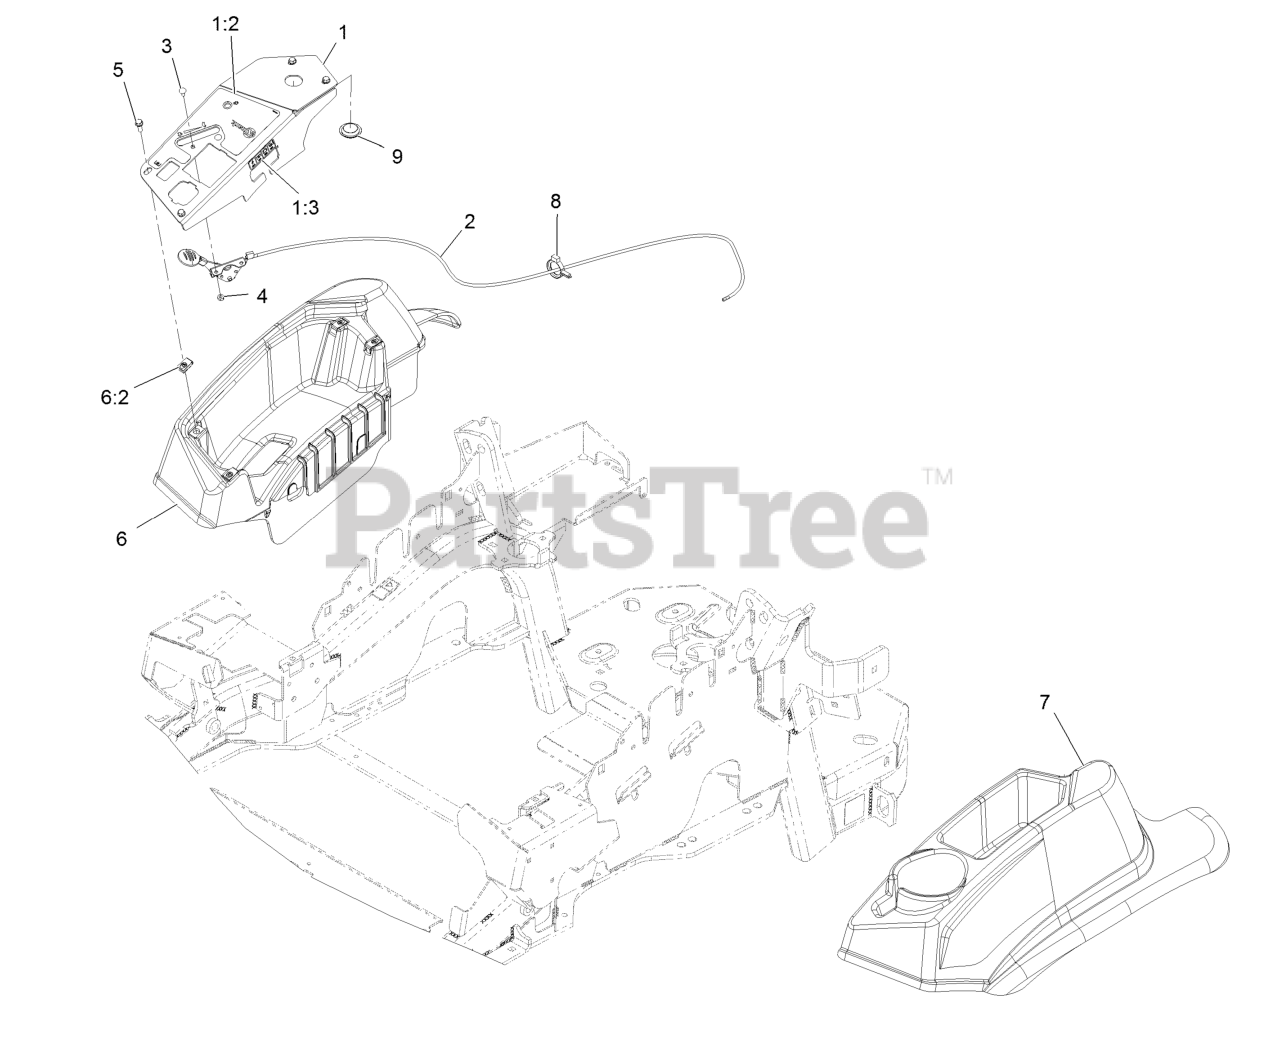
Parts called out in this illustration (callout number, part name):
1	ASM,CONTROL PANEL W/DECAL
1:2	DECAL-CONTROL PANEL EFI
1:3	DECAL-FUSES
2	ASM,THROTTLE CABLE
3	BOLT-CARR
4	NUT-LOCK, NI
5	SCREW-HWH
6	CONSOLE,RH AS ASM
6:2	Nut-Retainer-Panel 1/4-20
7	CONSOLE, LH AS
8	CLAMP-HOSE
9	PLUG-PLASTIC
